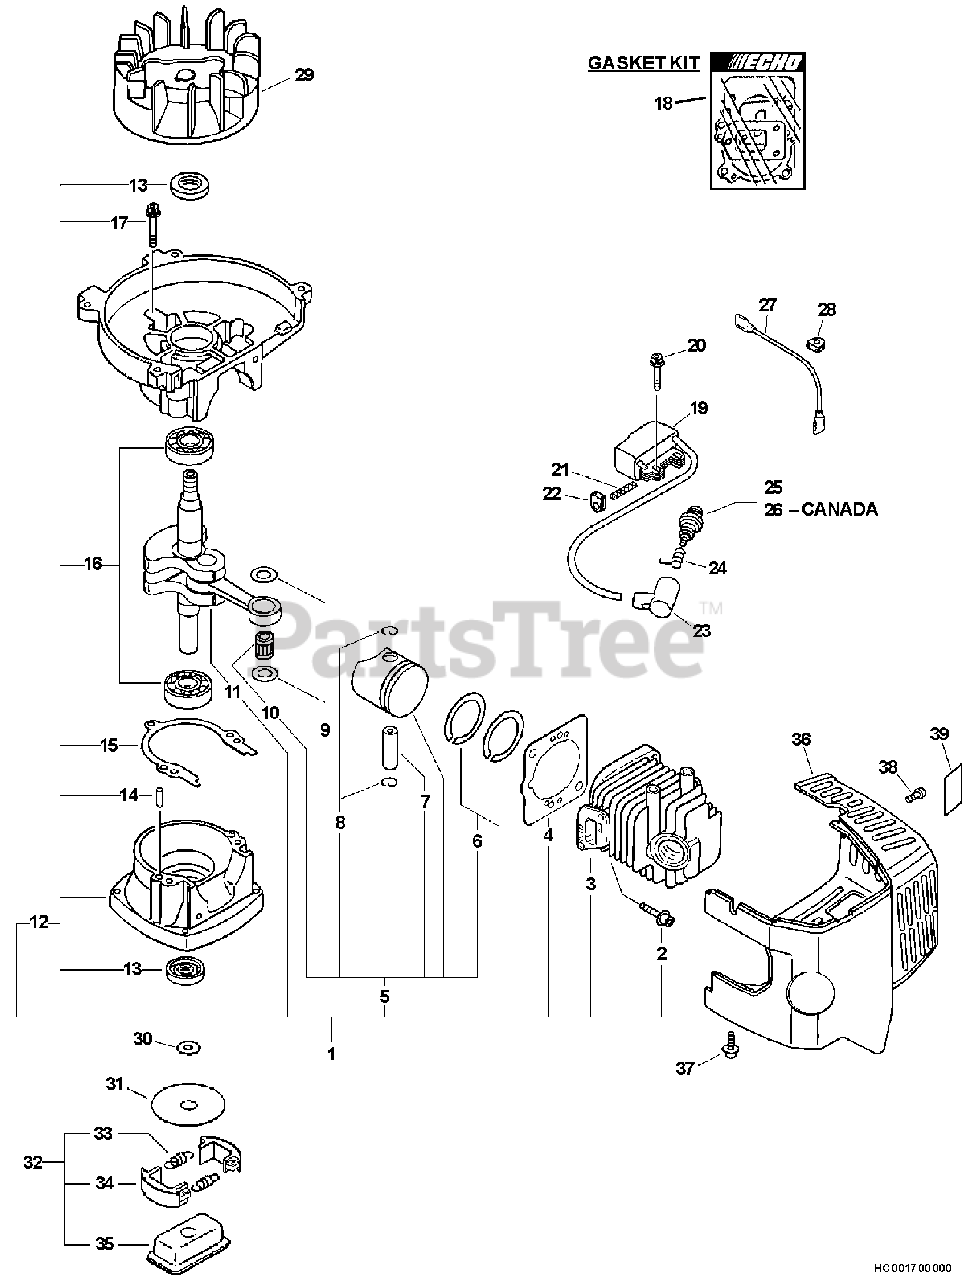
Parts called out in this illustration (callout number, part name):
1	SHORT BLOCK -- SB1067
2	SCREW - 5X22
3	CYLINDER
4	GASKET, CYLINDER
5	PISTON KIT
6	RING, PISTON
7	PIN, PISTON
8	RING, RETAINING
10	BEARING, NEEDLE - 8
11	CRANKSHAFT ASSY
12	CRANKCASE KIT
13	SEAL, OIL
14	PIN - LOCATING
15	GASKET, CRANKCASE
16	BEARING, BALL - 6201
17	SCREW - 5X28
18	GASKET KIT
19	COIL, IGNITION
20	SCREW - 4X20
21	TUBE, INSULATOR
23	CAP, SPARK PLUG
24	TERMINAL, SPARK PLUG CAP
25	SPARK PLUG -- BPM-8Y
26	SPARK PLUG -- BPMR-8Y
27	LEAD - IGNITION
29	FLYWHEEL
30	WASHER, CLUTCH
31	PLATE, CLUTCH
32	CLUTCH ASSY
33	SPRING, CLUTCH
34	SHOE, CLUTCH
35	HUB, CLUTCH
36	COVER, ENGINE - GRAY
37	SCREW - 4X20
38	SCREW - 4X8
39	LABEL - HOT SURFACE
